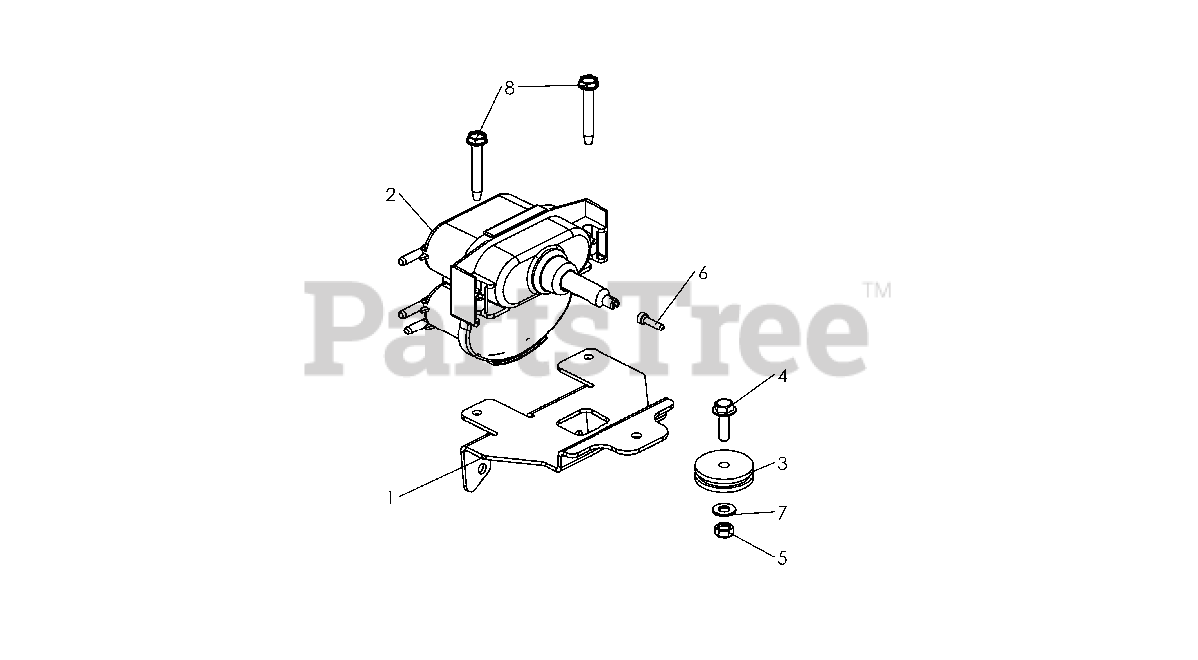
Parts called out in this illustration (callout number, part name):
3	ROLLER
5	Blocking nut M 6 Z
7	WASHER
8	SCREW
